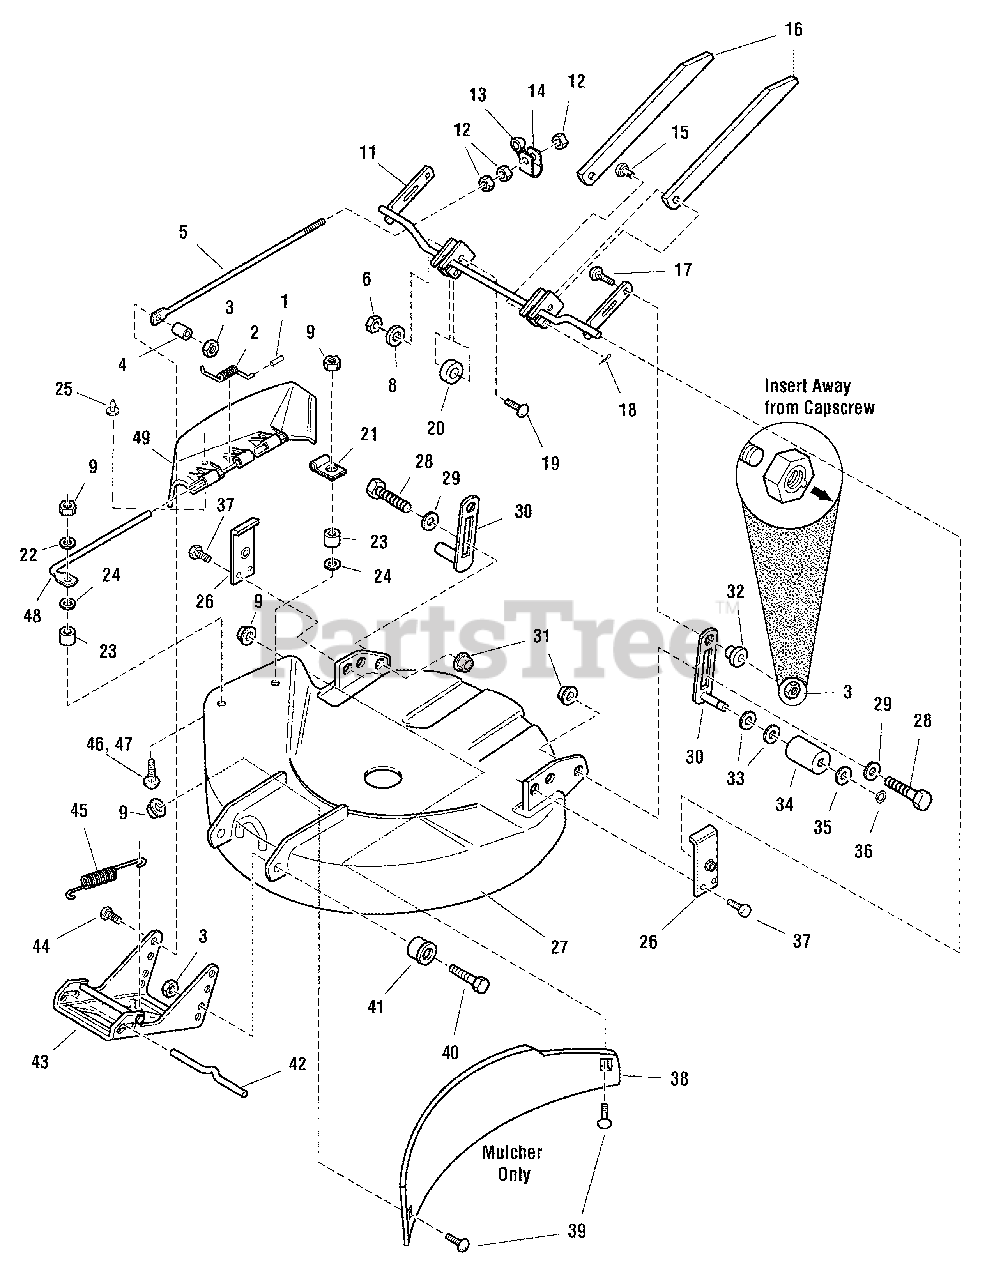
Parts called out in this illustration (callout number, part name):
1	CAP, Spring End
2	SPRING, Torsion
3	NUT, Hex, ALUM Lock, 3/8
5	ROD, Adjustment
6	NUT, Hex Flange Whiz Lock, 5/16-18
9	NUT, Hex ESNA, 1/4-20
11	ARM ASSEMBLY, Mower
12	JAMNUT, Hex, 3/8-16
13	SPACER
15	PIN, Locking
16	BAR, Mower Transport
17	CARRIAGE BOLT, 3/8-16 x 1-1/2
18	PIN, Retaining
19	CARRIAGE BOLT, 5/15-18 x 1-1/4
22	WASHER, Plain (1 Required for Export)
23	SPACER (Export)
24	PUSHNUT, 1/4
26	PLATE, Pivot Support
27	HOUSING ASSEMBLY, 30" (Orange)
27	HOUSING ASSEMBLY, 30" (Red)
27	HOUSING ASSEMBLY, 30" (Black)
28	BOLT, Shoulder, 3/8-16 X 1.34
29	WASHER, Flat
30	SUPPORT ASSEMBLY, Roller
31	NUT, Hex, Flange, Whizlock, 3/8-16
32	NUT, Hex Adjusting, .99 DIA .687
33	WASHER, 5/8
35	WASHER, 21/32 x 1-1/8 x 1/16
36	RING, Retaining
37	CAPSCREW, Taptite, 5/16-18 x 3/4
38	PLATE, Discharge (30" Mulcher)
39	CARRIAGE BOLT, 5/16-18 x 3/4, G5
40	CAPSCREW, Hex, 3/8-16 x 1 3/8
42	ROD, Latch, Hitch
43	HITCH ASSEMBLY
44	CAPSCREW, Hex Head, 3/8-16 x 1
46	CARRIAGE BOLT, 1/4-20 x 3/4
47	CARRIAGE BOLT, 1/4-20 x 1-1/4 (Export)
48	ROD, Deflector
49	DEFLECTOR, Plastic
